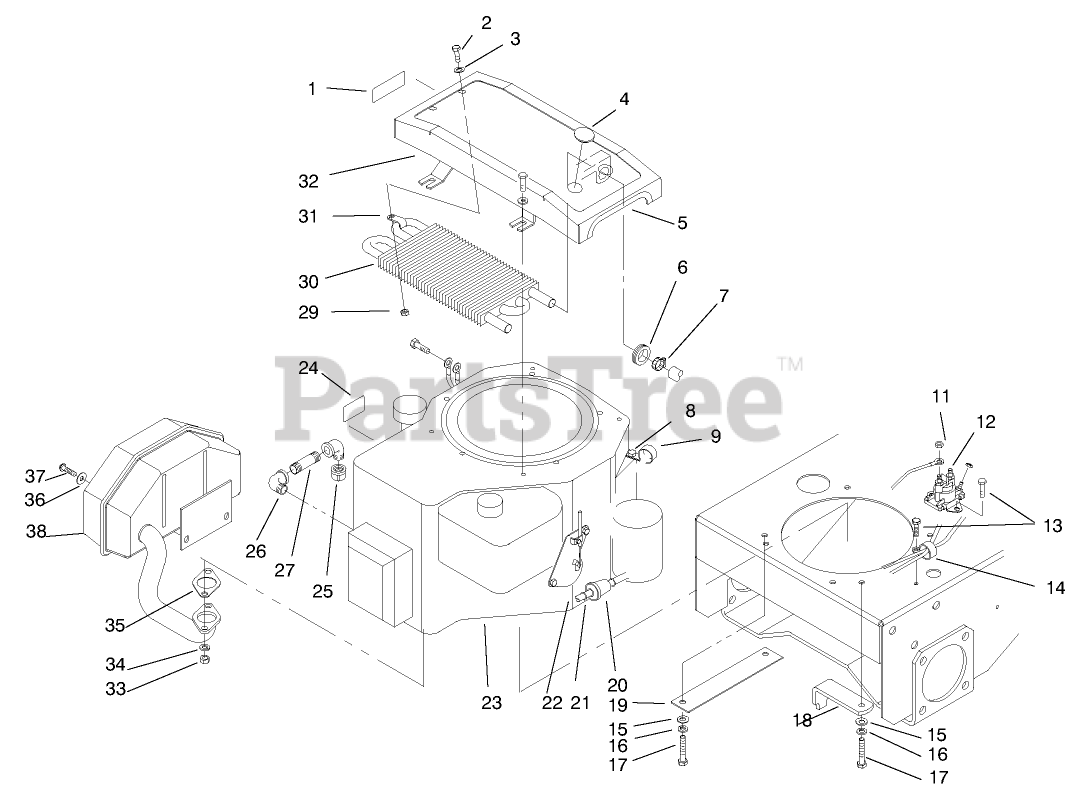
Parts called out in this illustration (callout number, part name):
1	DECAL-SHUT OFF, FUEL
2	WASHER-FLAT
3	SCREW-HH
4	PLUG-PLASTIC
5	TRIM-MOUNT, COOLER
6	GROMMET
7	CLAMP-HOSE
8	SCREW-HWHTF
9	CLAMP-R
11	NUT-KEPS
12	Solenoid
13	SCREW-HWH
14	CLAMP-R
15	WASHER-PLAIN
16	WASHER-LOCK
17	SCREW-HH
18	RETAINER-CLUTCH
19	GUARD-PULLEY
20	FILTER-FUEL
21	CLAMP-HOSE
22	HOSE-FUEL
23	Engine-Kohler
24	DECAL-SURFACE, HOT
25	CAP-PIPE
26	ELBOW-STREET, 90 DEG
27	NIPPLE
29	NUT-LOCK, NI
30	Cooler-Oil
31	CLAMP-R
32	MOUNT-COOLER
33	NUT-MUFFLER
34	WASHER-LOCK
35	GASKET-EXHAUST
36	WASHER-FLAT
37	SCREW-MUFFLER
38	Muffler (Supplied w/Eng)
